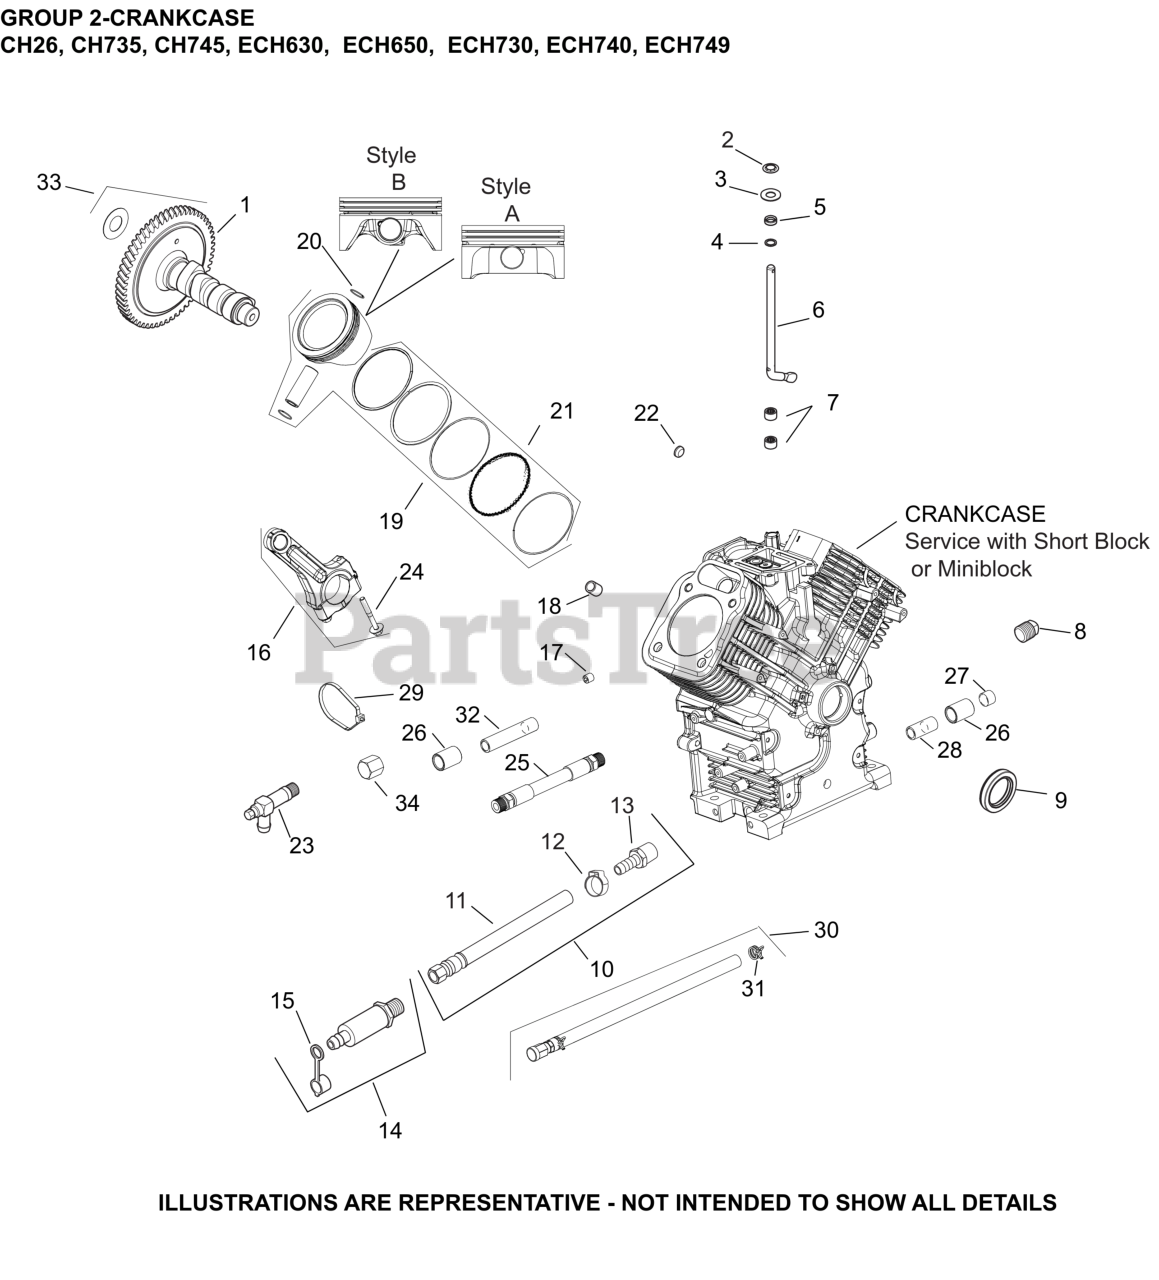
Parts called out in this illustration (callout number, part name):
1	KIT, CAMSHAFT
2	RETAINER, RING
3	WASHER, FLAT 9 MM
4	WASHER, FLAT 11/32"
5	SEAL, GOVERNOR CROSS SHAFT
6	SHAFT, GOVERNOR CROSS
8	PLUG, HD PIPE 3/8"
9	SEAL, OIL (HELIX LIP)
16	ROD, ASSEMBLY CONNECTING
18	PIN, LOCATING
19	KIT,PSTN/RNG STYLE B(STD)
19	KIT,PSTN/RNG STYLE B(.08)
19	KIT,PSTN/RNG STYLE B(.25)
19	KIT,PSTN/RNG STYLE B(.50)
20	RETAINER, PISTON PIN
21	RING SET(STD)STYLE B-1.2mm Tp RING THICK
21	RING SET(.08)STYLE B-1.2mm RING THICK
21	RING SET(.25)STYLE B-1.2mm Tp RING THICK
21	RING SET(.50)STYLE B-1.2mm Tp RING THICK
22	PLUG, CUP
24	KIT, ROD BOLTS-(#25086677S)
